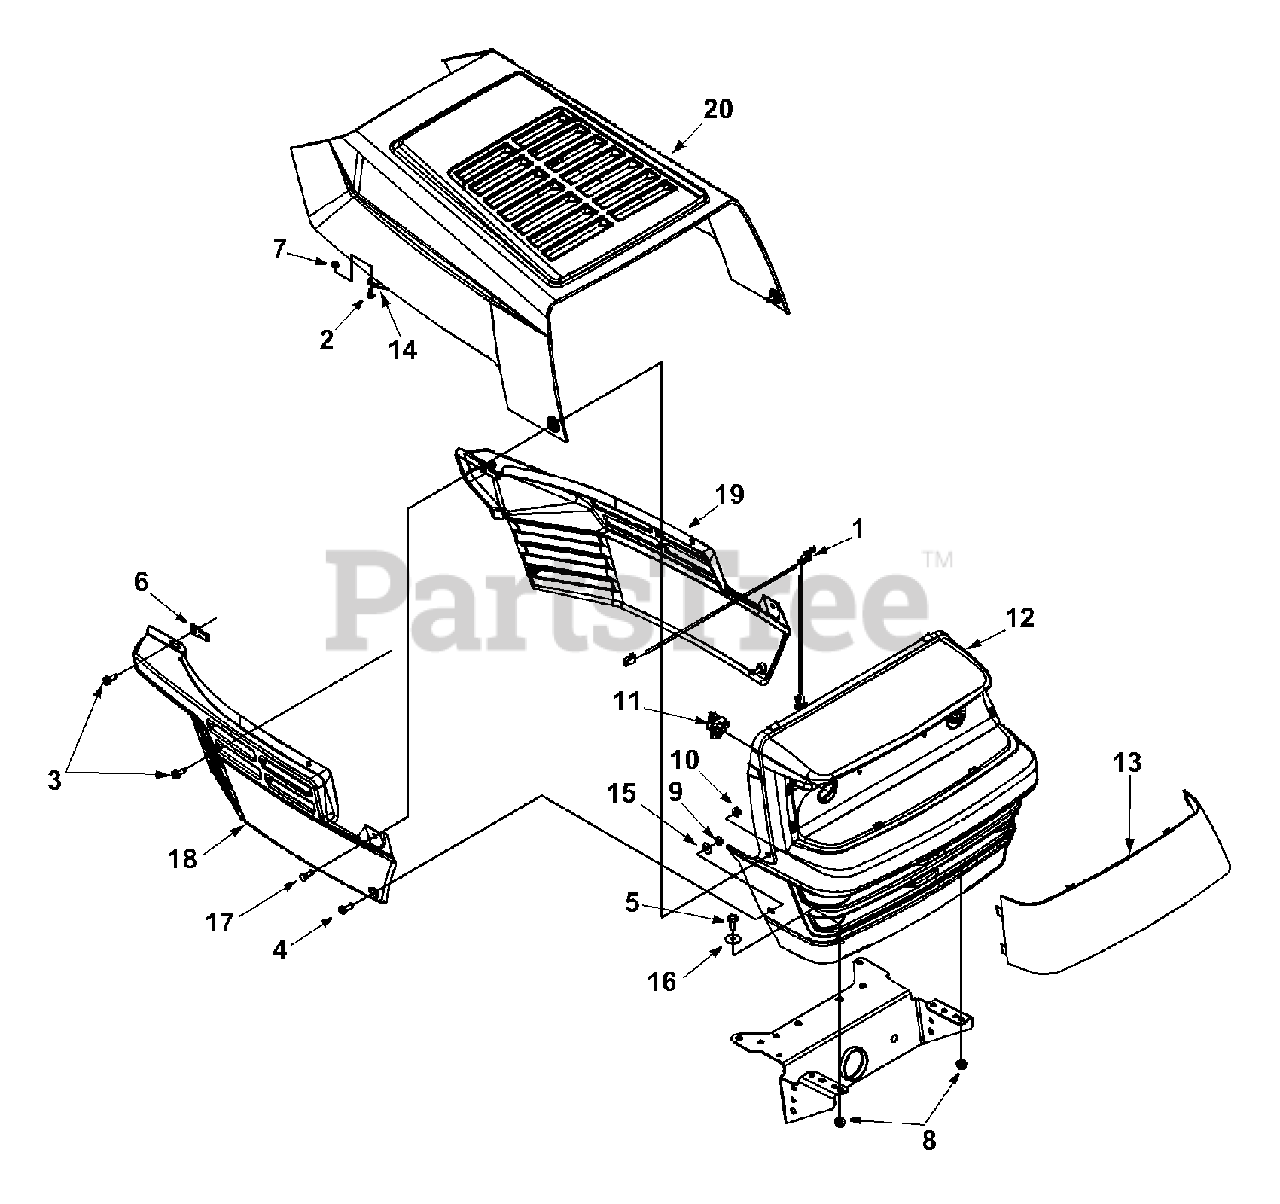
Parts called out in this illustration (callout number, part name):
1	Harness Assembly
2	Truss Mach. Scr. #10-24 x .5"
3	Hex TT-Tap Scr. 1/4-20 x .75" Lg.
4	Pan Hd. Scr. 1/4-20 x .75" Lg.
5	Hex Bolt 5/16-18 x .75" Lg.
6	Speed Nut 1/4-20 Thd.
7	Hex Sems Nut #10-24 Thd.
8	Flange L-Nut 5/16-18 Thd.
9	Hex Sems Nut 1/4-20 Thd.
10	Hex Flange L-Nut 1/4-20 Thd.
11	Socket
12	Grill
13	Lens
14	Hood Latch
15	Bell-Wash. 1/4" I.D.
16	Fl-Wash. .34" I.D. x 1" O.D.
17	Shld. Bolt .375" Dia. x .125" Lg.
